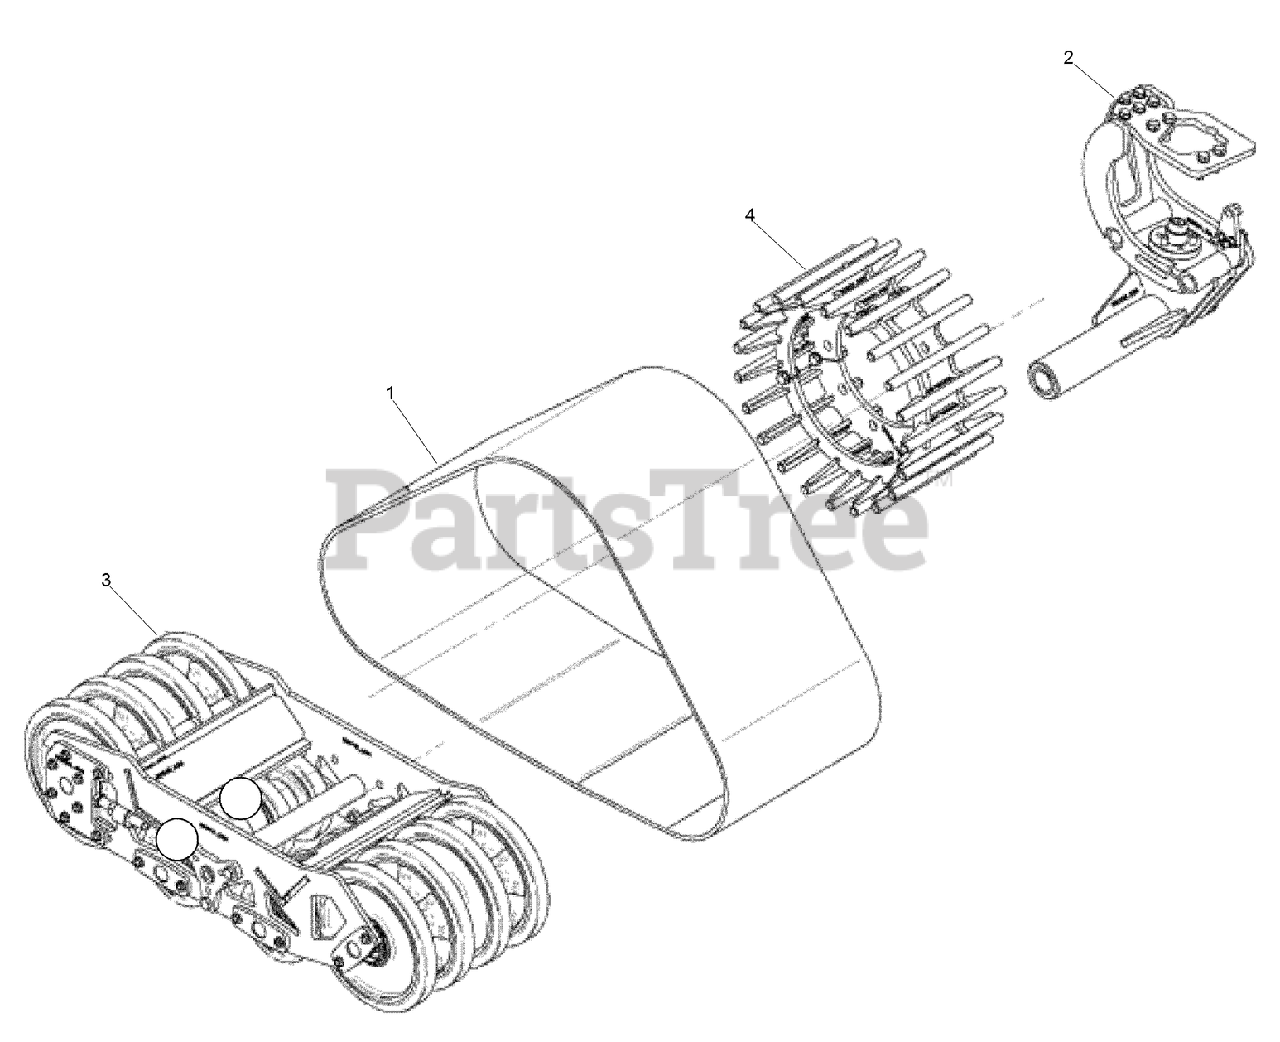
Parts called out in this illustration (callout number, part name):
1	TRACK-RUBBER, 511E, 19.5 IN
2	ASSEMBLY - Track Mounting Structure, Front Left / Rear Right
3	ASSEMBLY - Track Chassis
4	ASSEMBLY - Track Sprocket
